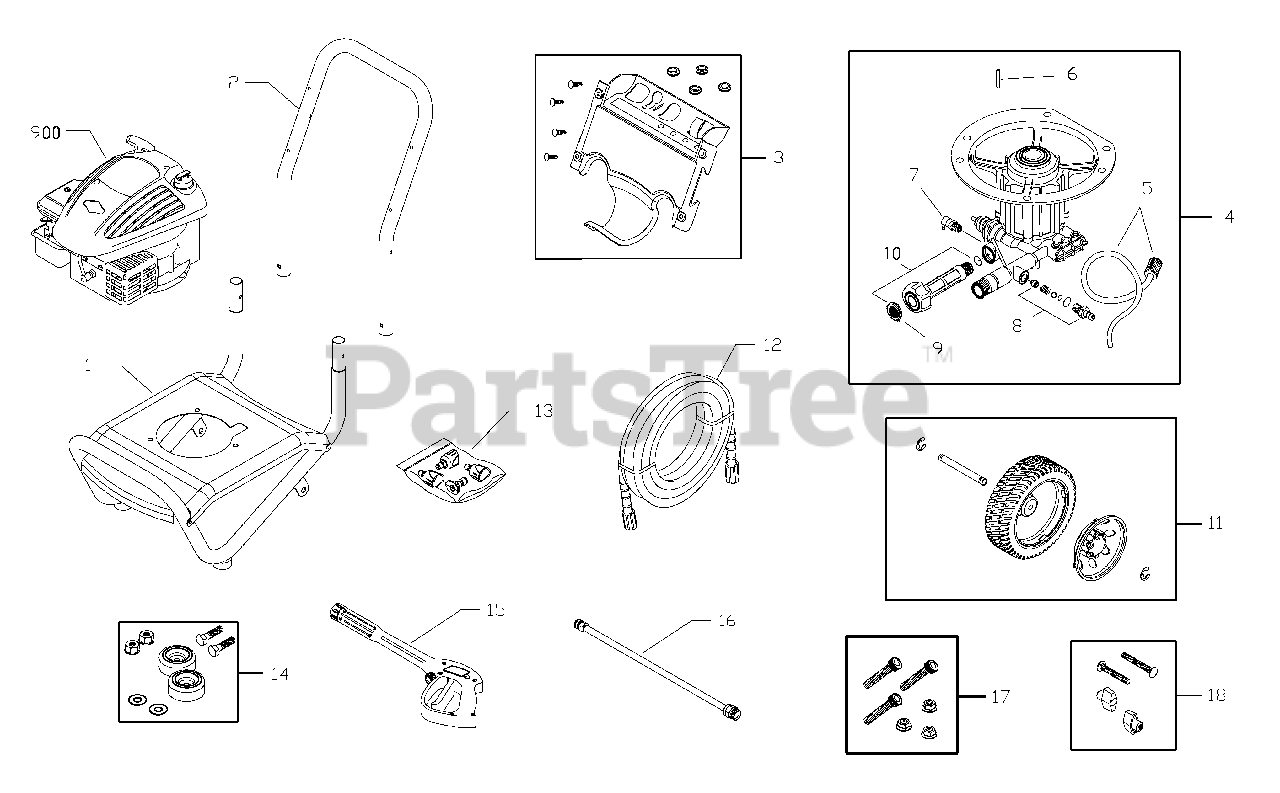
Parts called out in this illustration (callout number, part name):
3	Kit, Billboard Assy w/Decal & Clips
5	Kit, Chemical Hose
7	Valve, Thermal Relief
8	Kit, Chemical Injection
10	Kit, Water Inlet
13	Kit, Nozzles
14	Kit, Vibration Mount
15	Gun
16	Extension, QC
17	Kit, Pump Mounting Hardware
18	Kit, Handle Connector
900	* Engine
